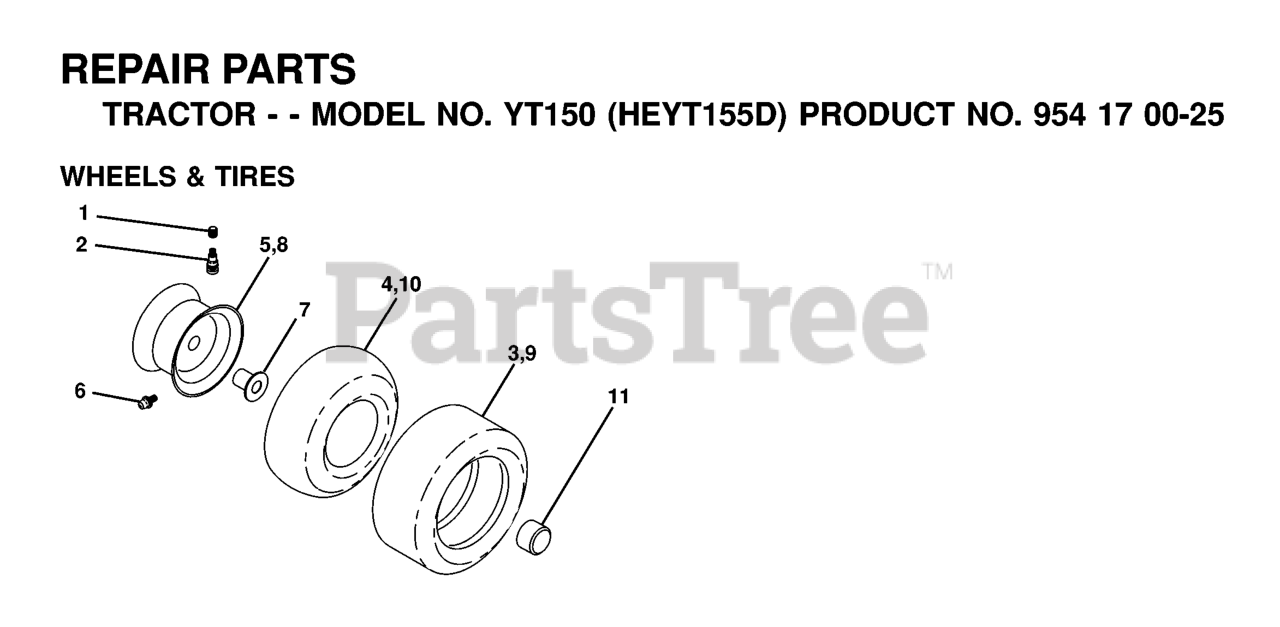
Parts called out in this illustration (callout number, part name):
1	SCREW.HEX.WASH.HD.TAPPING
2	WASHER, LOCK 3/8
3	LOCKNUT
5	PIN.SPIROL.FLARED
6	LEVER ASM CRT
8	PANEL.INDICATOR.SHIFT.BLACK
11	GUARD.RT TILLER.21 HD.CE
12	NUT
14	SPACER-SPLIT.327 X .42
15	WASHER
16	SHEAVE, TRANSMISSION
18	SPACER SPLIT
19	RETAINING RING LT
23	WHEEL.DR.LH.16X4X8.TILLER.SILV
25	SPRING TI
26	GUARD.BELT.TILLER.8HP.ORANGE
27	BELT, DRIVE
28	PULLEY-IDLER TI
30	BRACKET.IDLER.ASM.SHORT
32	SHAFT, IDLER ARM
37	RPSHEAVE.3.50.TILLER.ZINC.SUBA
39	CAP.PLUNGER.BLACK
62	BOLT 5/16-18X4 1/2
63	BRACKET.ASM.GRD.BELT.INTEK.PNT
66	GUIDE.BELT.TILLER.HD.004
67	WASHER
